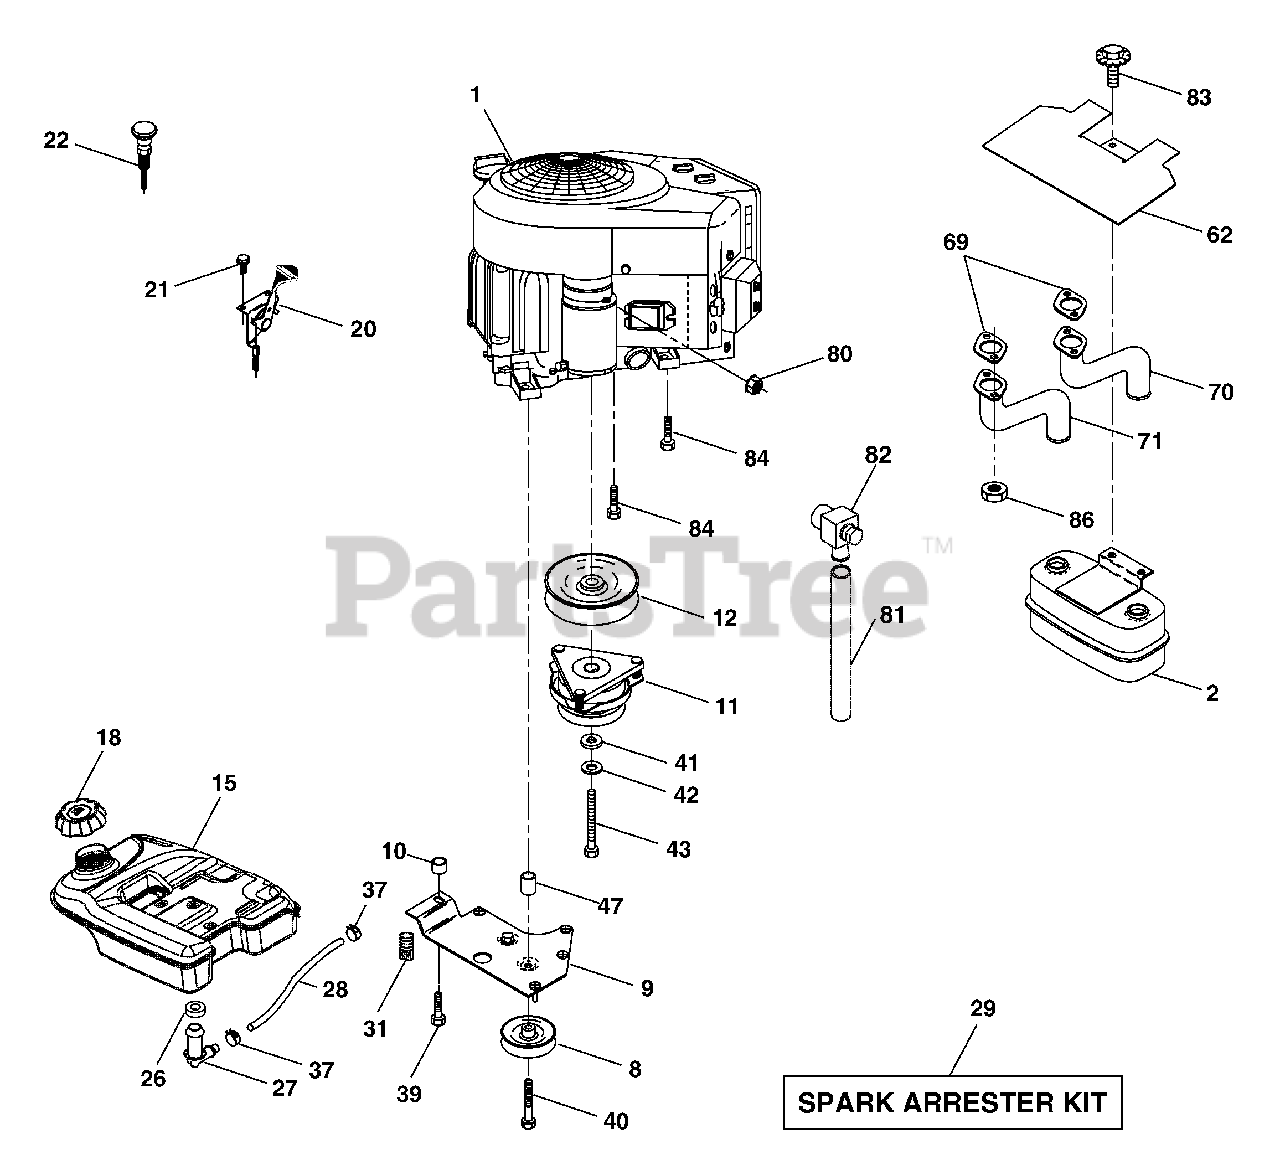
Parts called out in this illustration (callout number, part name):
2	Muffler Side
8	Pulley V-Idler
9	Keeper Asm. Belt Engine VGT
11	Clutch Electric
12	Pulley Engine VGT Elect Clutch
18	Cap Fuel
20	Control Throttle
21	Screw HWHD Hi-Lo #13-16 x 3/4
22	Control Choke
26	Bushing
27	Stem Tank Fuel
28	Fuel Line
29	Spark Arrester Kit
31	Clip Push-In Hinged
37	Clamp Hose
39	Screw TT 3/8-16 x 2-1/4 unc
40	Screw TT 3/8-16 x 4 unc
41	Washer 1-1/2 OD x 15/32 ID x .250
42	Washer Lock 7/16
43	Bolt Hex 7/16-20 X 3.75 Gr. 5
62	Shield Heat Muffler
69	Gasket
70	Tube Exhaust RH
71	Tube Exhaust LH
80	Nut Flange M8-1.25
81	Tube Drain Oil Easy
82	Valve Oil Drain
83	Bolt 5/16-18 unc x 1-3/4 W/Sems
84	Screw 3/8-16 x 1-1/2
86	Nut Hex Flange Toplock M8-1.25
